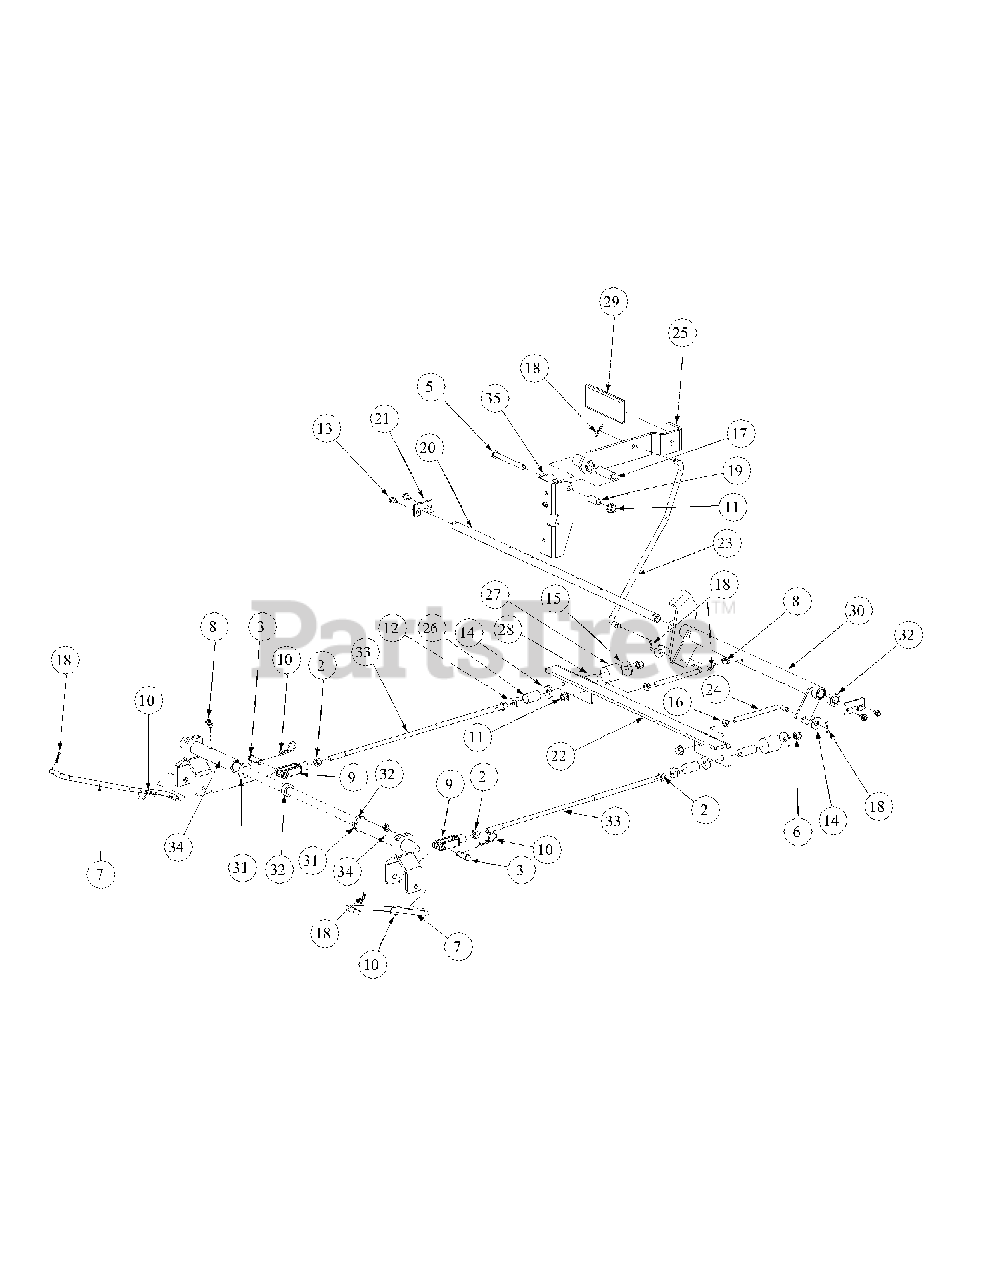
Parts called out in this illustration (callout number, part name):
2	Hex Nut, 3/8-16
3	Clevis Pin, 3/8 x 1-1/8
5	Hex Cap Screw, 3/8-16 x 3-1/2 OR
5	Hex Cap Screw, 3/8-16 x 3-1/4
6	Nylock Nut, 3/8-16
7	Linkage Brake Rod
8	Grease Fitting, 1/4 -28, 90 degree
9	Yoke, 3/8-16
10	Hair Pin, 3/8" - 1/2"
11	Flange Lock Hex Nut, 3/8-16
12	Shoulder Nut
13	Screw, 1/4-20 x 1-1/2
14	Flat Washer, .406 ID x 1.0 OD x .105
15	Flat Washer, .411 x 1.25 x .100
16	Jam Nut, 3/8-16
17	Spacer, .375 x .50 x 1.75
18	Cotter Pin, .072 x 1.12 Lg
19	Spacer, .375 x .50 x 1.02 Lg
20	Bellecrank Mounting Shaft
21	Parking Brake Shaft Holder
22	Brake Bracket
23	Brake Rod
24	Connector Rod, 3/8 OD x 5.75
25	Brake Handle
26	Neutral Brake Spring
27	Force Brake Spring
28	Center Brake Hose
29	Parking Brake Grip
30	Brake Bearing Hub
31	Flat Washer, 5/8
32	Shaft Collar, .625 ID x 1" OD x .438
33	Connector Rod, 3/8 OD x 17.88 Lg
34	Rear Brake Arm Assembly
35	Parking Brake Mounting Bracket
